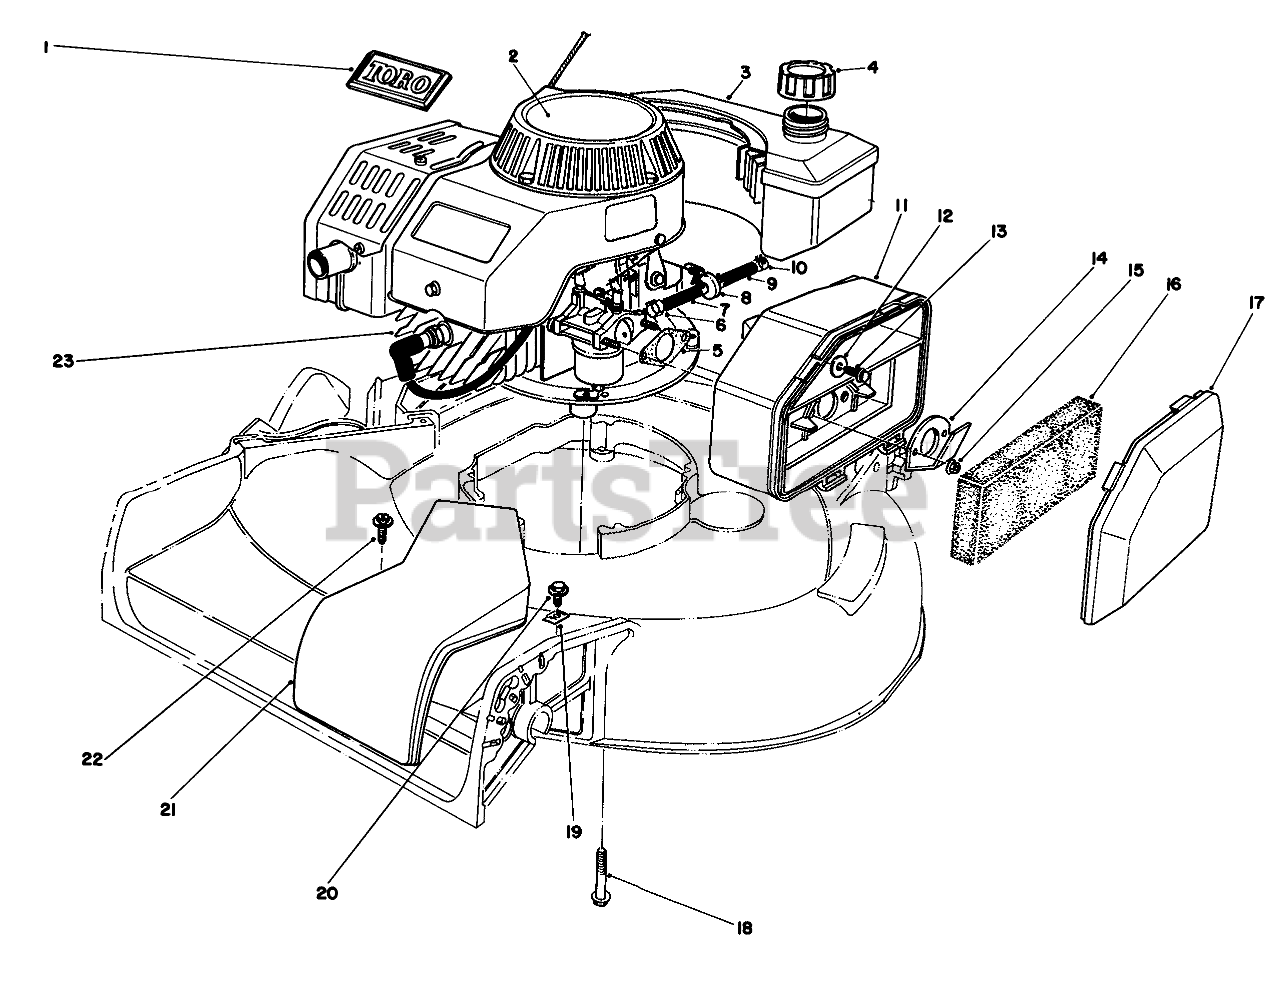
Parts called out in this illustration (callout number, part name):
1	TORO LOGO PLT
2	DECAL- 2 CYC RECOIL
3	FUEL TANK ASM
4	GAS CAP ASM
5	GASKET-AIR CLEANER
6	FUEL LINE CLAMP
7	HOSE-FUEL
8	FILTER-FUEL
9	HOSE-FUEL
10	CLAMP-FUEL LINE
11	AIR CLEANER
12	WASHER-FLAT
13	SCREW-HH
14	SPIT BACK DEFLECTOR
15	NUT-LOCK
16	FILTER
17	AIR CLEANER COVER
18	FLG SCREW,3/8-16X2.000
19	Cable Clamp
20	SCREW-HWHTF
21	Cow-Belt
22	SCREW
23	Engine (Complete)
